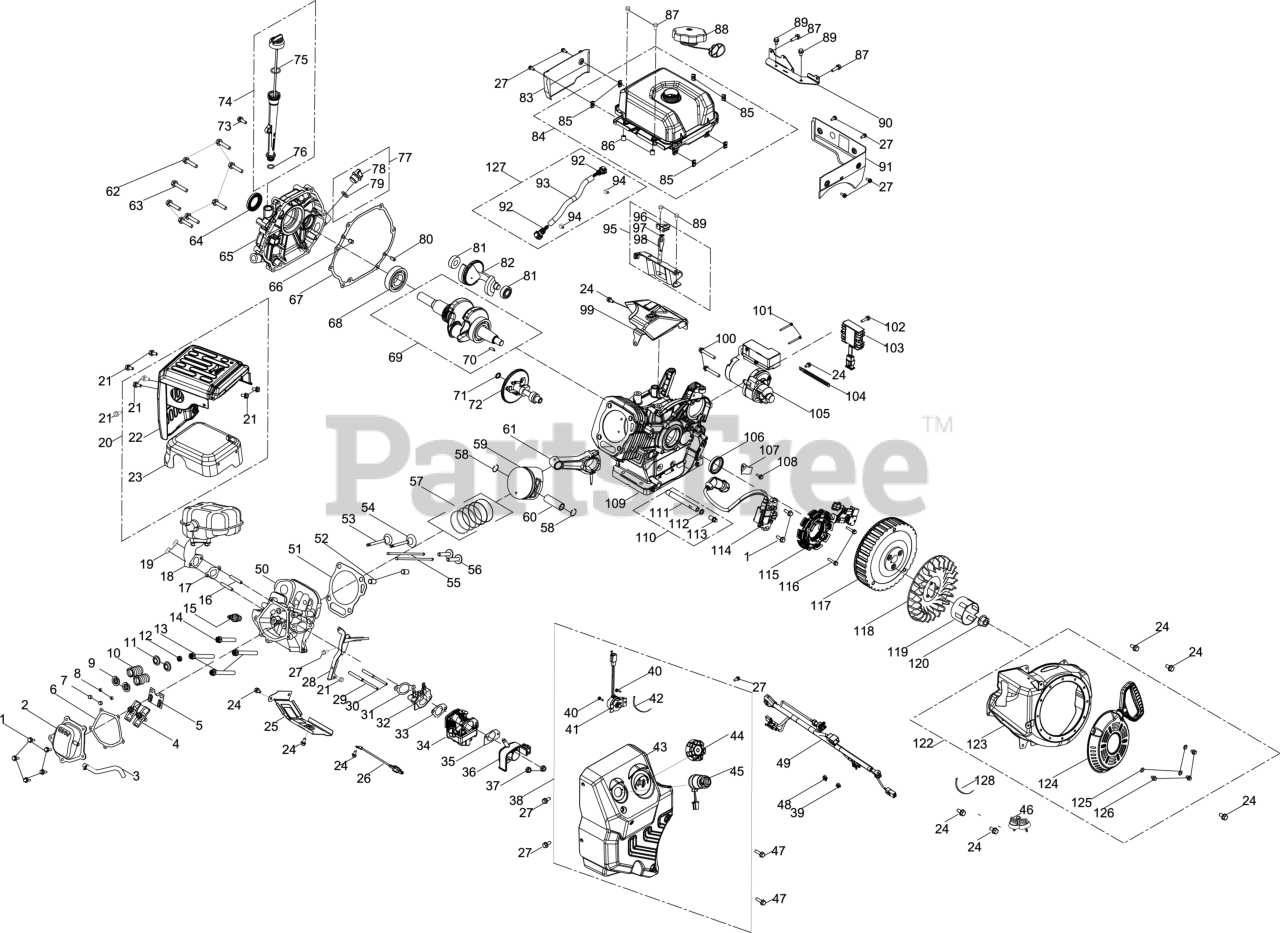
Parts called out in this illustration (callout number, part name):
1	BOLT M6 x 16
2	VALVE COVER
3	BREATHER HOSE
4	ROCKER ARM ASSEMBLY
5	PUSH ROD GUIDE
6	VALVE COVER GASKET
7	EXHAUST VALVE ADJUSTER
9	VALVE SPRING SEAT
10	SPRING VALVE
11	VALVE SPRING RETAINER
12	INTAKE VALVE SEAL
13	SCREW M10-1.25 x 87 x GR10.9
14	SCREW M10-1.25 x 65 x GR10.9
15	SPARK PLUG (F6RTC/RN11YC/BPR6ES)
16	EXHAUST STUD
17	MUFFLER GASKET
20	MUFFLER SHIELD
21	BOLT M6-1 x 10 GR8.8
22	MUFFLER SHIELD (OUTER)
23	MUFFLER SHIELD (INNER)
24	BOLT M6-1 x 12 GR8.8
25	CYLINDER BAFFLE
26	TEMP SENSOR
27	BOLT M6-1 x 14 GR8.8
28	RECOIL SNOW GUARD
29	STUD M6 x 123
30	CARBURETOR STUD
31	CARBURETOR INSULATOR GASKET
33	CARB GASKET
34	FUEL INJECTOR
35	AIR FILTER GASKET
36	HEATER BOX
38	CONTROL PANEL
39	FUEL LINE SUPPORT CLAMP
41	SPEED CONTROL SWITCH
42	CABLE TIE - 3 x 150
43	CONTROL PANEL
44	SPEED CONTROL KNOB
45	KEY SWITCH
46	KEY SWITCH
47	SCREW M6-1 x 20 CL5.8
48	WIRE SUPPORT CLAMP
49	EFI ENGINE HARNESS
50	CYLINDER HEAD
51	CYLINDER HEAD GASKET
52	DOWEL PIN 12x20
53	EXHAUST VALVE
54	INTAKE VALVE
57	PISTON RING SET
58	PISTON PIN SNAP RING
61	CONNECTING ROD
62	SCREW M8-1.25 x 38 GR10.9
63	BOLT M8 x 45
65	CRANKCASE COVER
67	CRANKCASE COVER GASKET
68	BALL BEARING
69	CRANKSHAFT ASSEMBLY
70	WOODRUFF KEY
73	BOLT M6-1 x 18 GR8.8
74	DIPSTICK OIL ASSEMBLY
77	OIL DRAIN PLUG
80	DOWEL PIN 7 X 14
81	BALL BEARING
82	BALANCE SHAFT
83	FUEL TANK BACK PANEL
85	THREADED TAB
89	BOLT M8-1.25 x 14 GR8.8
90	FUEL TANK BASE BRACKET
91	FUEL TANK FRONT PANEL
92	QUICK DISCONNECT FUEL LINE
93	FUEL HOSE 8 x 14 x 290
95	FUEL TANK MOUNT BRACKET
96	RUBBER GROMMET
97	RUBBER GROMMET
98	FUEL TANK MOUNTING BRACKET
99	GOVERNOR GEAR BRACKET
100	BOLT M8-1.25 x 55 GR8.8
102	BOLT M6-1 x 25 GR8.8
104	SUPPORT CLAMP
105	ELECTRIC STARTER
107	ALTERNATOR WIRE CLAMP BRACKET
108	BOLT M6-1 x 8 GR8.8
110	OIL DRAIN PIPE
111	OIL DRAIN PIPE
112	FLAT WASHER
113	OIL DRAIN PLUG
114	IGNITION COIL
115	CHARGING COIL
116	BOLT-M6-1 x 30 GR8.8
118	COOLING FAN
119	STARTER CUP
120	FLYWHEEL NUT M16X1.5
122	RECOIL START
123	BLOWER HOUSING
124	RECOIL START ASSEMBLY
125	FLAT WASHER
126	BOLT M6 x 10
127	FUEL LINE ASSEMBLY
128	CABLE TIE 3x150
